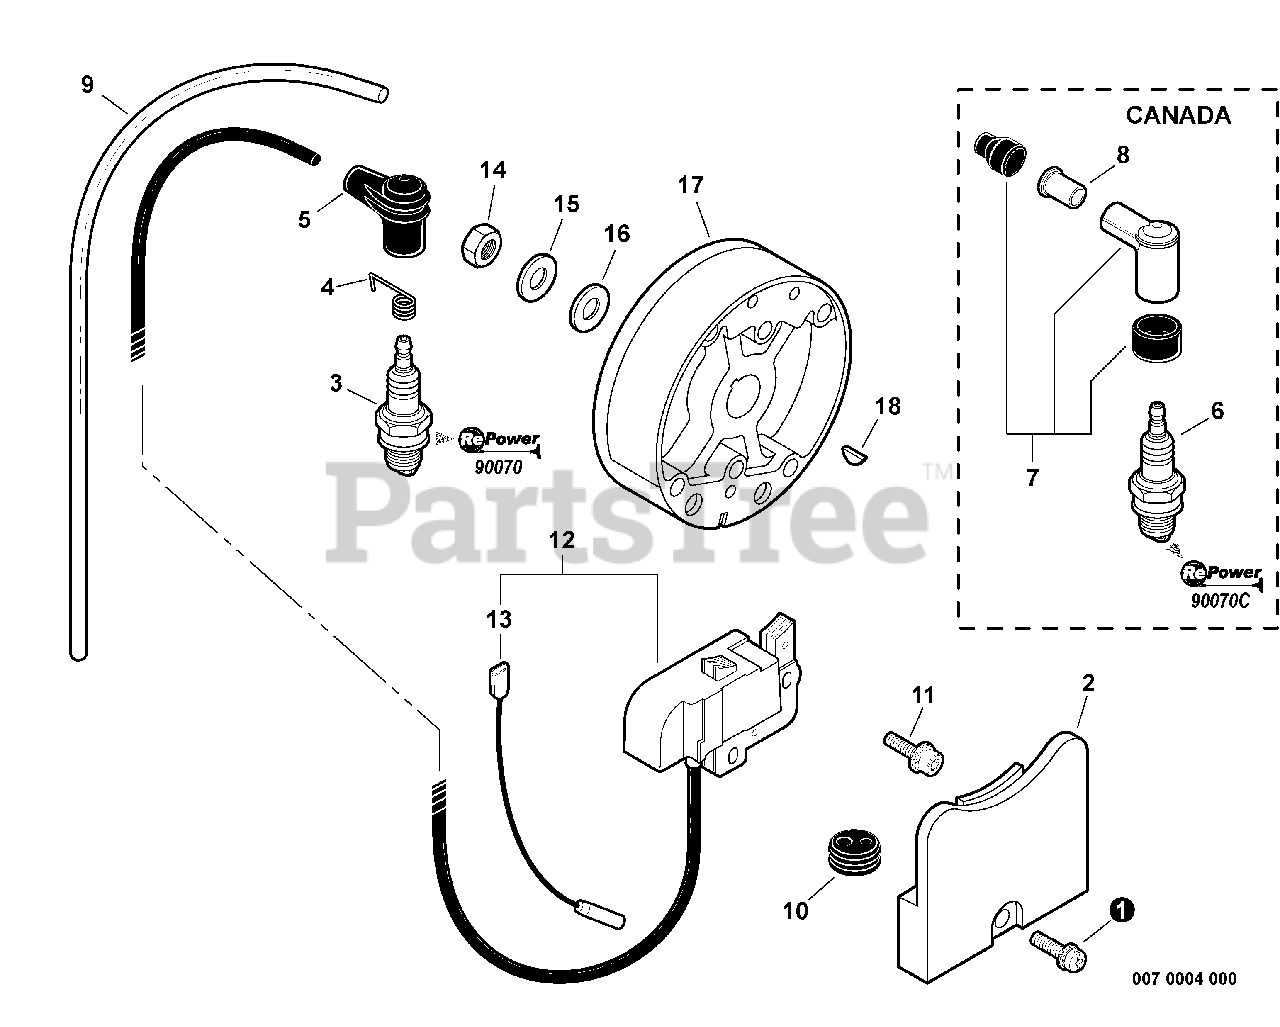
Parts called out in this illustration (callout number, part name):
1	BOLT 5×22
2	COVER, DUST
3	SPARK PLUG - BPM8Y
4	TERMINAL, SPARK PLUG
5	CAP, SPARK PLUG
6	SPARK PLUG - BPMR8Y
7	CAP, SPARK PLUG
8	ADAPTOR, SPARK PLUG - CAP
9	TUBE, VINYL 6.3×8×380
11	BOLT 5×22
12	COIL ASSY, IGNITION
13	LEAD - IGNITION
15	WASHER, SPRING 10
16	WASHER, SPRING 10
17	FLYWHEEL
18	KEY, WOODRUFF 3×14
19	TUNE-UP KIT - REPOWER
20	TUNE-UP KIT - REPOWER
